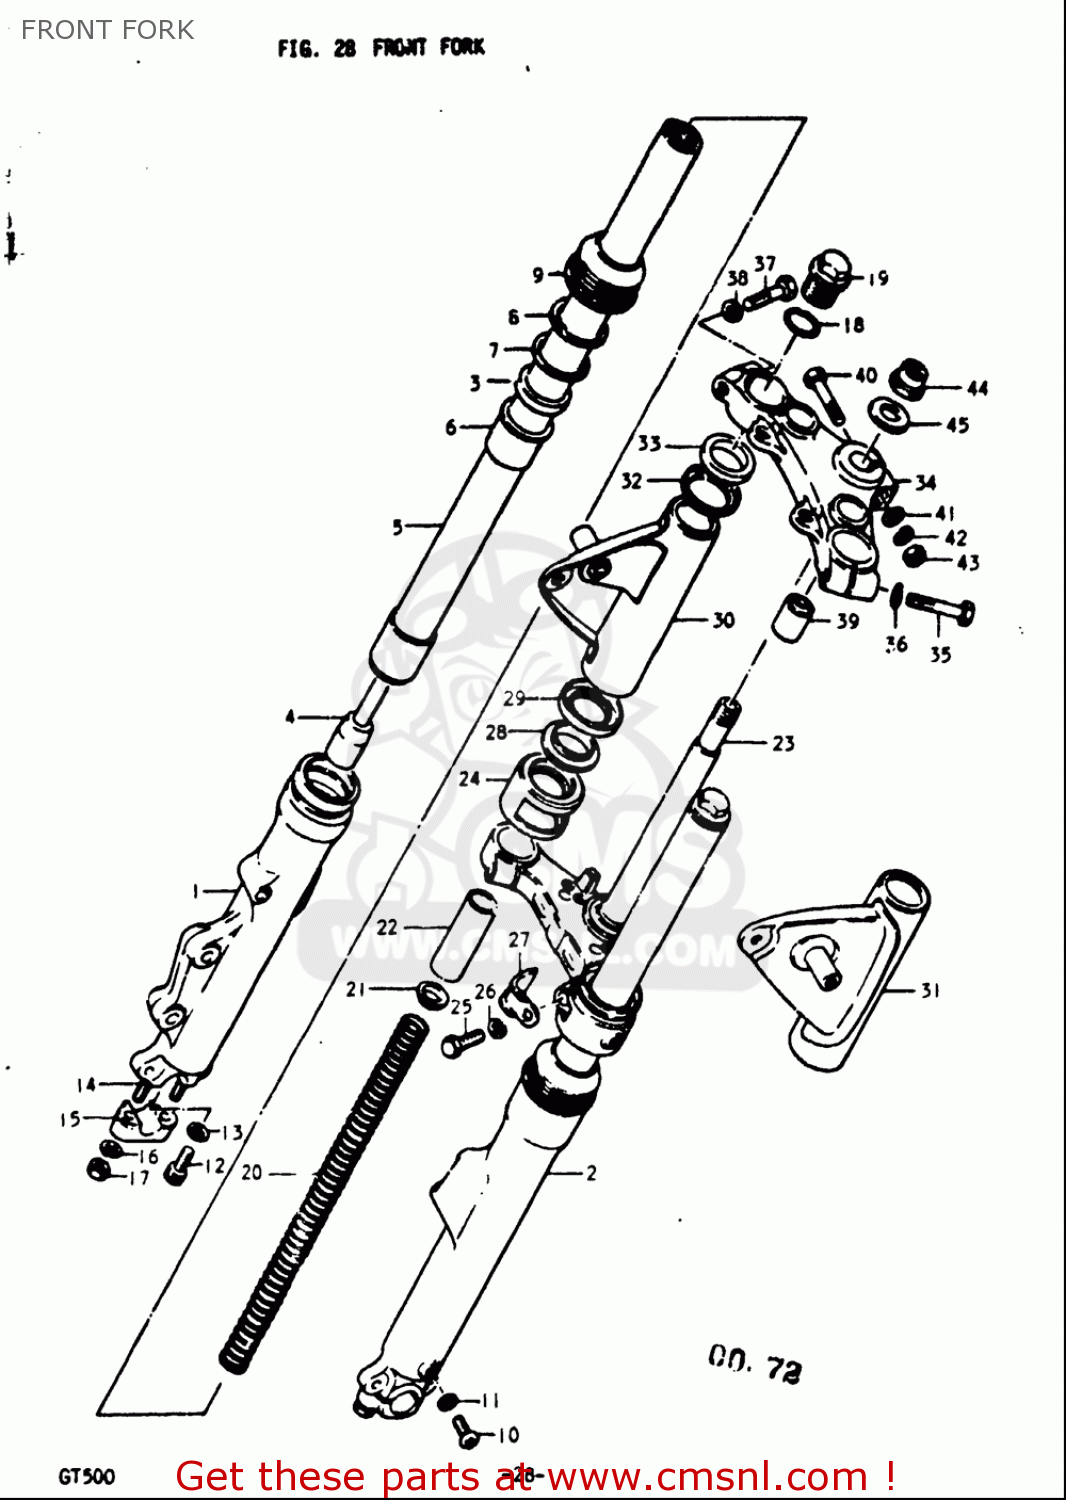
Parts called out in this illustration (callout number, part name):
3	SEAL,OIL
5	TUBE,FORK,INNER
10	SCREW
11	GASKET,DRAIN,PLUG (NAS)
13	GASKET (NAS)
14	BOLT,STUD
16	WASHER,LOCK
17	NUT
18	O-RING,FORK FITTING BOLT
19	CAP,FORK INNER TUBE
20	SPRING,FRONT
